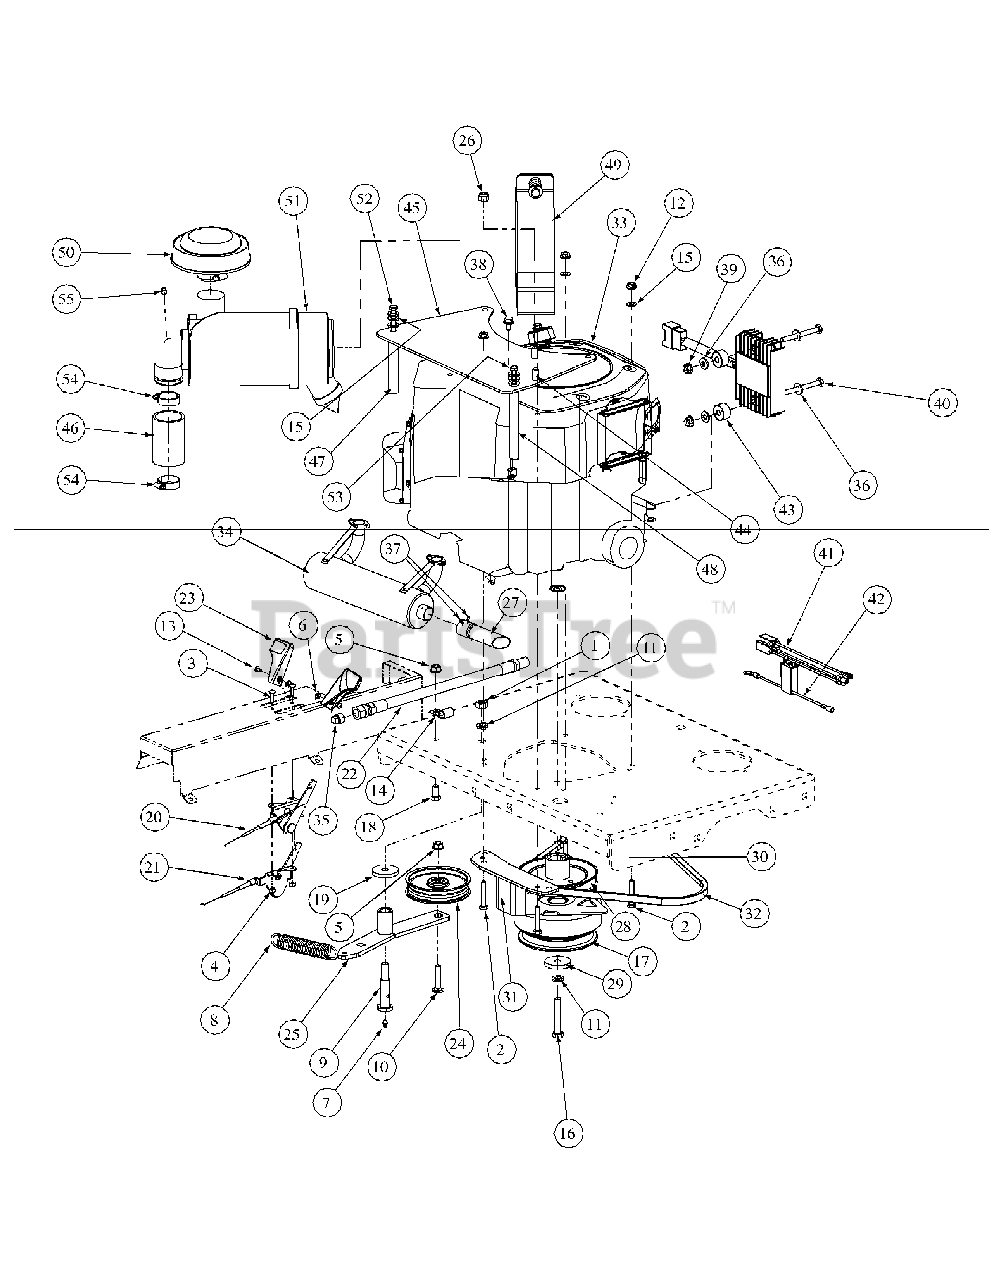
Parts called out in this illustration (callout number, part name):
1	Hex Nut, 7/16-14
2	HHCS, 5/16-18, 1-3/4
3	Round Hd. Machine Screw, 10-32 x 3/4
4	Lock Nut, Nylon Insert, 10-32
5	Flange Lock, Hex Nut, 3/8-16
6	Nut Washer, W/Star, 8-32
7	Grease Fitting, 1/4-28 x 3/16
8	Extension Spring, 1.0 OD x 5.125
9	Shoulder Screw, 7/16-14
10	Hex Carriage Screw, 3/8-16, 1.75
11	Lock Washer, 7/16
12	Hexflange Lock Nut, 5/16-18
13	Machine Screw, 8-32, .375
14	Clip, Heat Shield Cable
15	Flat Washer, 5/16
16	Capscrew, 7/16-20 x 2.50
17	Clutch Brake, 1.125 ID
18	Hex Cap Screw, 3/8-16, .750
19	Flat Washer, 7/16 ID x 1.75 OD x .25
20	Choke Control Cable
21	Throttle Control Cable
22	Oil Drain Hose
23	Control Throttle Knob
24	Flat Pulley with Flanges
25	Engine Idler Arm Assembly
25	Bearing
25	Engine Idler Arm Assembly Cast
26	Nut, 5/16-18, Nylock
27	Straight Exhaust Pipe
28	Pump Drive Pulley
29	Flat Washer, 7/16 ID x 1.75 OD x .25
30	Key, 1/4 x 1/4 x 3
31	Retainer Clutch Assembly, Ogura
32	Belt, 51.2 Lg
33	Engine, 24HP Honda
34	Muffler
35	Pipe Plug, 3/8 NPT
36	Flat Washer, 1/4
37	Screw, 8-32 x 0.375
38	Screw, M6 x 1.0 x 12mm
39	Nut, 1/4-20, Hex Flange Lock
40	Hex Cap Screw, 1/4-20 x 2.50
41	Wire Harness Adaptor
42	Charge Regulator Wire
43	Spacer, .281 ID x .875 OD
44	Hex Cap Screw, 5/16-18 x 3/4
45	Aircleaner Bracket
46	Hose, 2.00 ID x .19 wall
47	Spacer, .370 ID x .500 OD x 3.45
48	Spacer, .370 ID x .500 OD x 4.08
49	Aircleaner Band
50	Aircleaner Hood
51	Engine Aircleaner
52	Bolt, 6MM x 120MM
53	Bolt, 6MM x 130MM
54	Hose Clamp
55	Nylon Pipe Plug, 1/8-27 NPT
